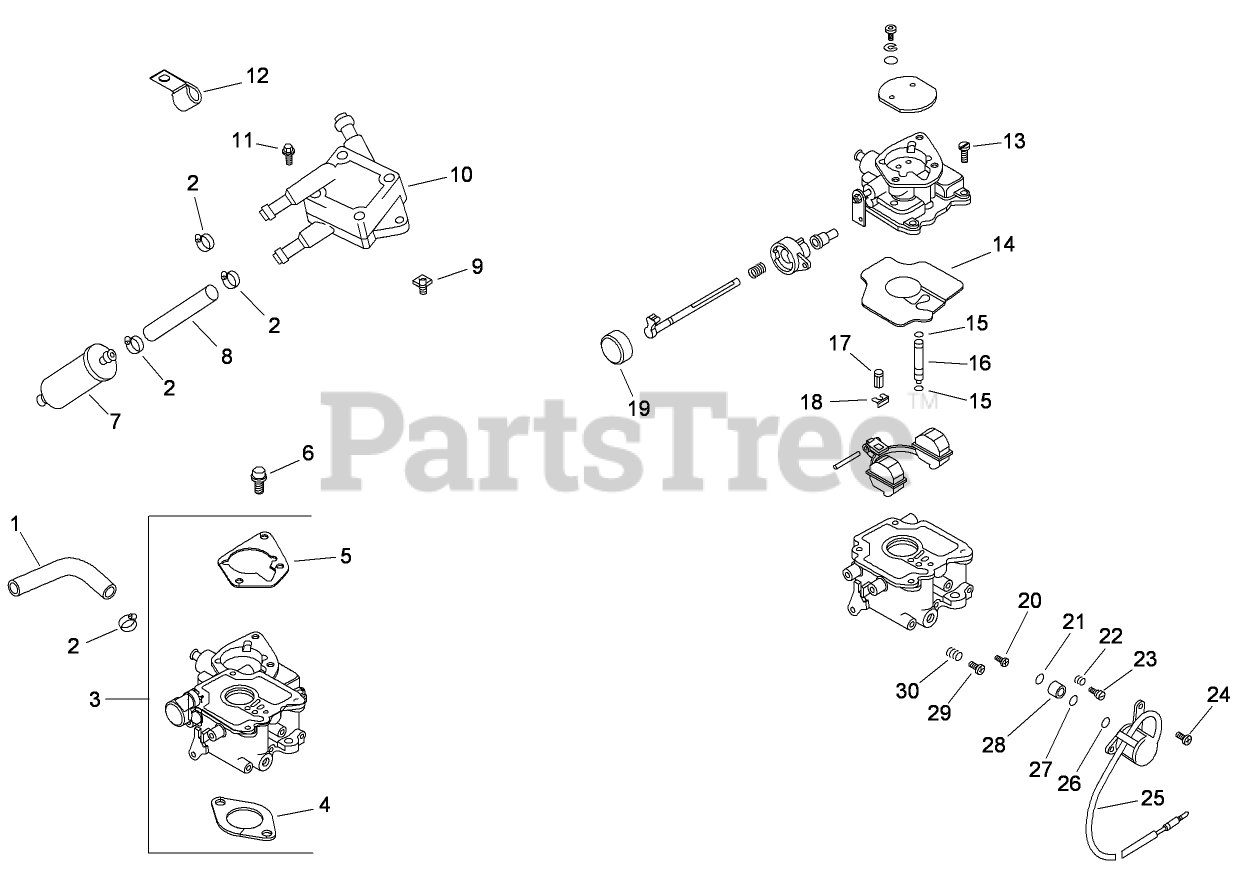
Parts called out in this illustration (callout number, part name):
1	LINE-FUEL (24.0 CUT TO LENGTH)
2	CLAMP-HOSE, SPRING (1/2)
3	Carburetor Kit (Includes 4, 5)
4	Gasket-Carburetor
5	GASKET-BASE, AIR CLEANER
6	SCREW-FLANGE (M6X1.0X30)
7	Filter-Fuel
8	Line-Fuel, Flexible (15.5)
9	Nut-Plastic
10	PUMP-FUEL
11	SCREW-TAP (M6X1.7X18)
12	CLIP-CABLE
13	Screw (Carburetor Body)
14	Gasket-Body, Carburetor
15	O-Ring (Slow Jet)
16	Jet-Slow
17	Valve-Needle, Inlet
18	Clip-Valve, Needle Inlet
19	Cap-Lever, Choke
20	Jet-Main
21	O-Ring (Solenoid)
22	Spring-Needle, Idle
23	Needle-Idle
24	Screw (Solenoid)
25	Solenoid ASM
26	O-Ring (Solenoid)
27	O-Ring (Solenoid)
28	Seat-Solenoid
29	Screw-Speed Adjust, Idle
30	Spring-Speed Adjust, Idle
